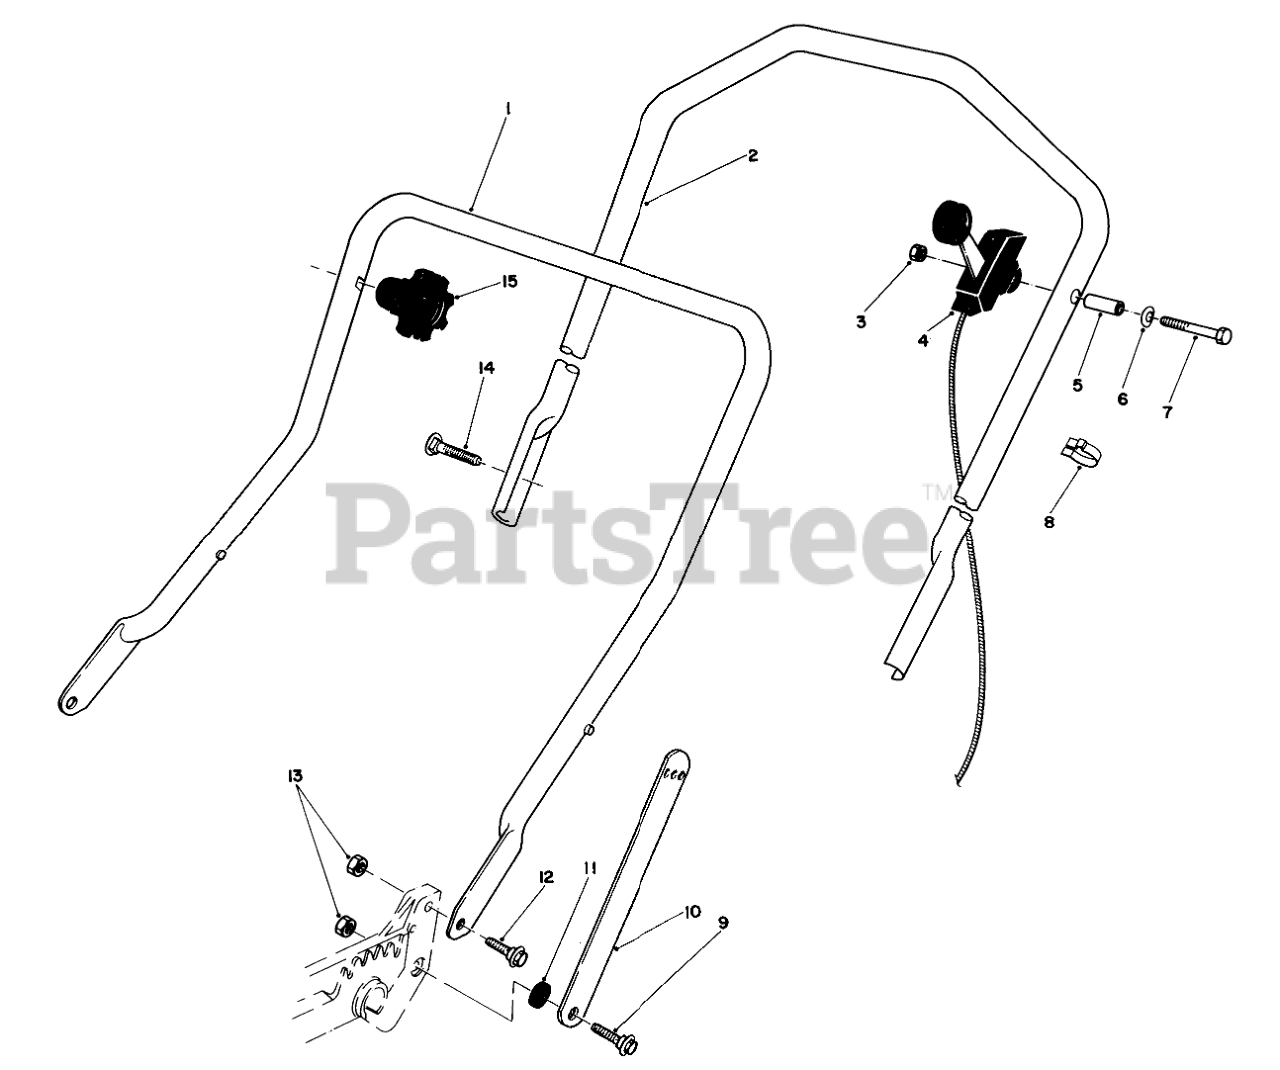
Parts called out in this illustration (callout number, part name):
1	Handle-Lower
2	UPPER HANDLE
3	NUT-LOCK
4	SERVICE THROTTLE CONTRO
5	Spacer
6	WASHER
7	SCREW-HH
8	BOWDEN CLIP
9	SCREW-SHOULDER
10	Handle Latch
11	SPACER
12	SCREW-SHOULDER
13	NUT-LOCK, NI
14	5/16-18 X 2 HNDLE SCREW
